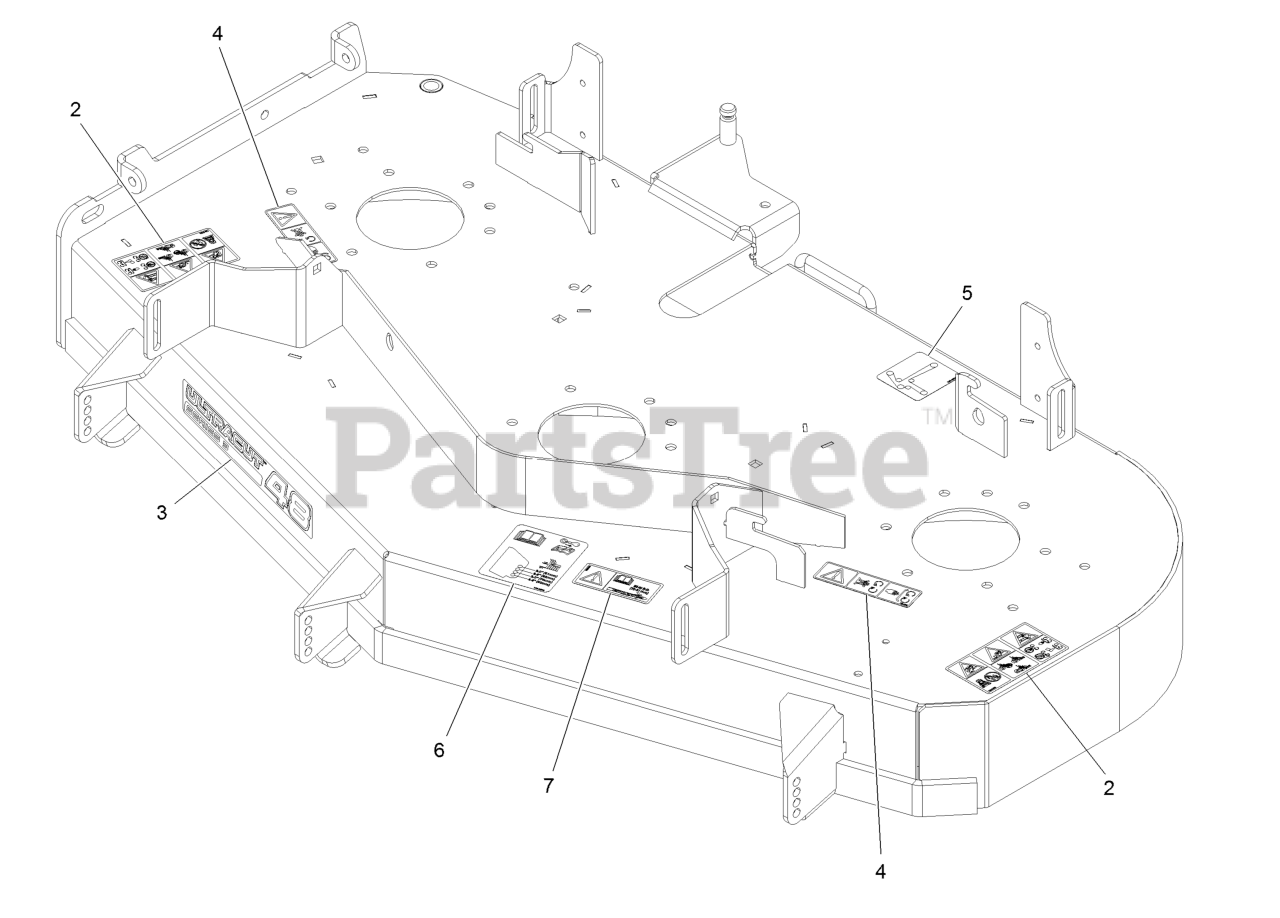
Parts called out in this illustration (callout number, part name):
2	Decal-Danger Thrown Objects
3	Decal-Ultracut 48 Series 3
4	Decal-Missing, Cover
5	Decal-Routing, Belt
6	Decal-Roller, Anti-Scalp
7	Decal-Bolt Torque
